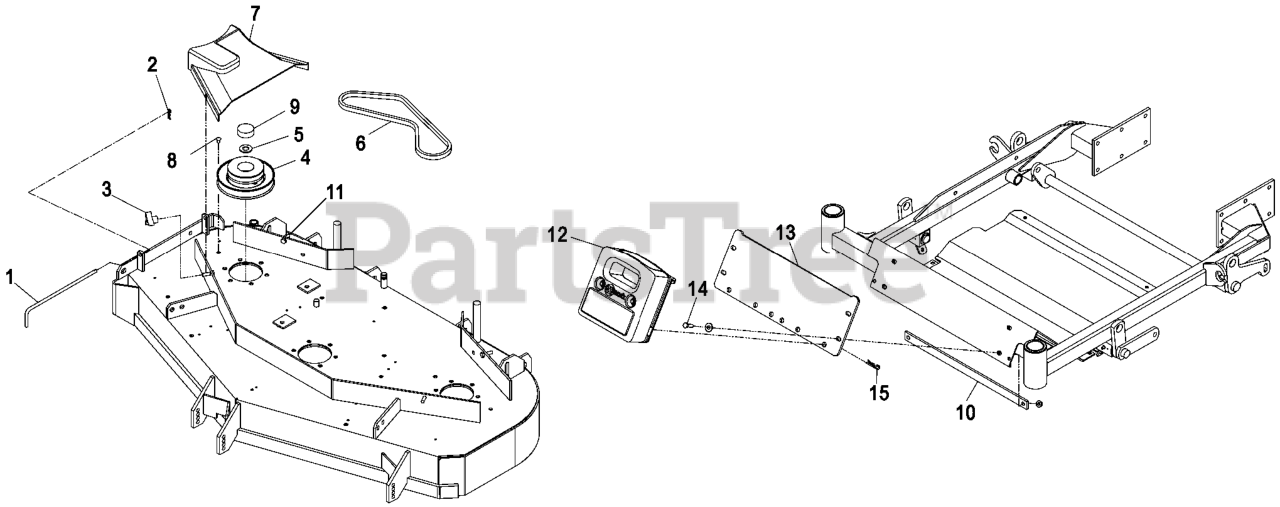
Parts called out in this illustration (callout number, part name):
1	PIN, CHUTE PIVOT PLTD
2	PIN-COTTER
3	KNOB-3 PRONG
4	SHEAVE, BLOWER DRIVE 52"
5	WASHER-FLAT
6	BELT, BLOWER 52"DECK
7	COVER, BELT 44/48
8	SCREW-HH
9	PLUG, BLACK NYLON 1.75
10	STRAP,WEIGHT MOUNT
11	BOLT-CARR
12	ASM,CAST WEIGHT
13	PLATE,WEIGHT ASM MOUNT
14	SCREW-HH
15	PIN-HAIR
